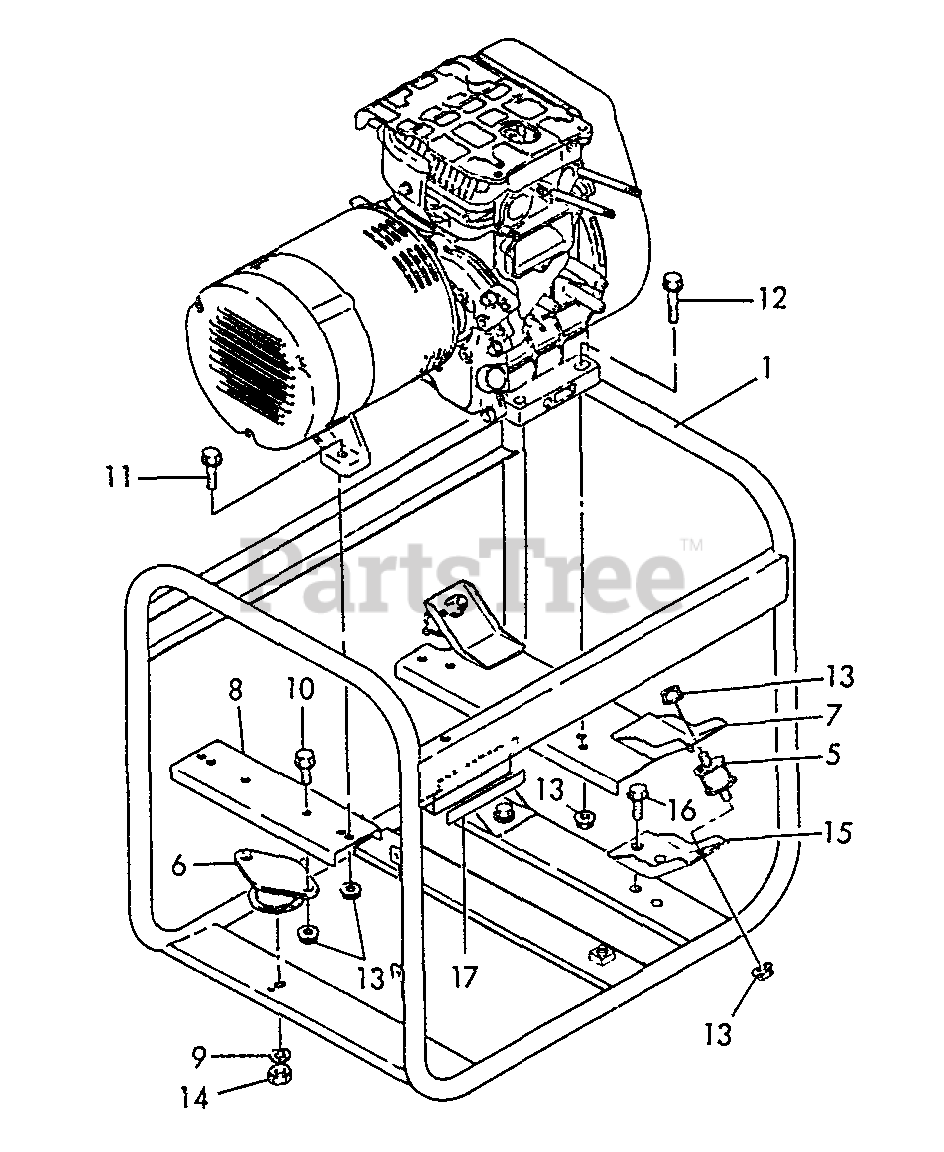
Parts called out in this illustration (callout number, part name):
1	FRAME ASSY
5	DAMPER, FRONT
6	DAMPER, REAR
7	STAY, DAMPER
8	STAY, REAR DAMPER
9	LOCKWASHER - 10
10	BOLT - 8X20 -- PLATED
11	BOLT - 8X30 -- PLATED
12	BOLT - 8X38 -- PLATED
13	NUT - 8
14	NUT - 10
15	DAMPER STAY, LOWER
16	BOLT - 8X16 -- PLATED
17	SHEET, FRAME
